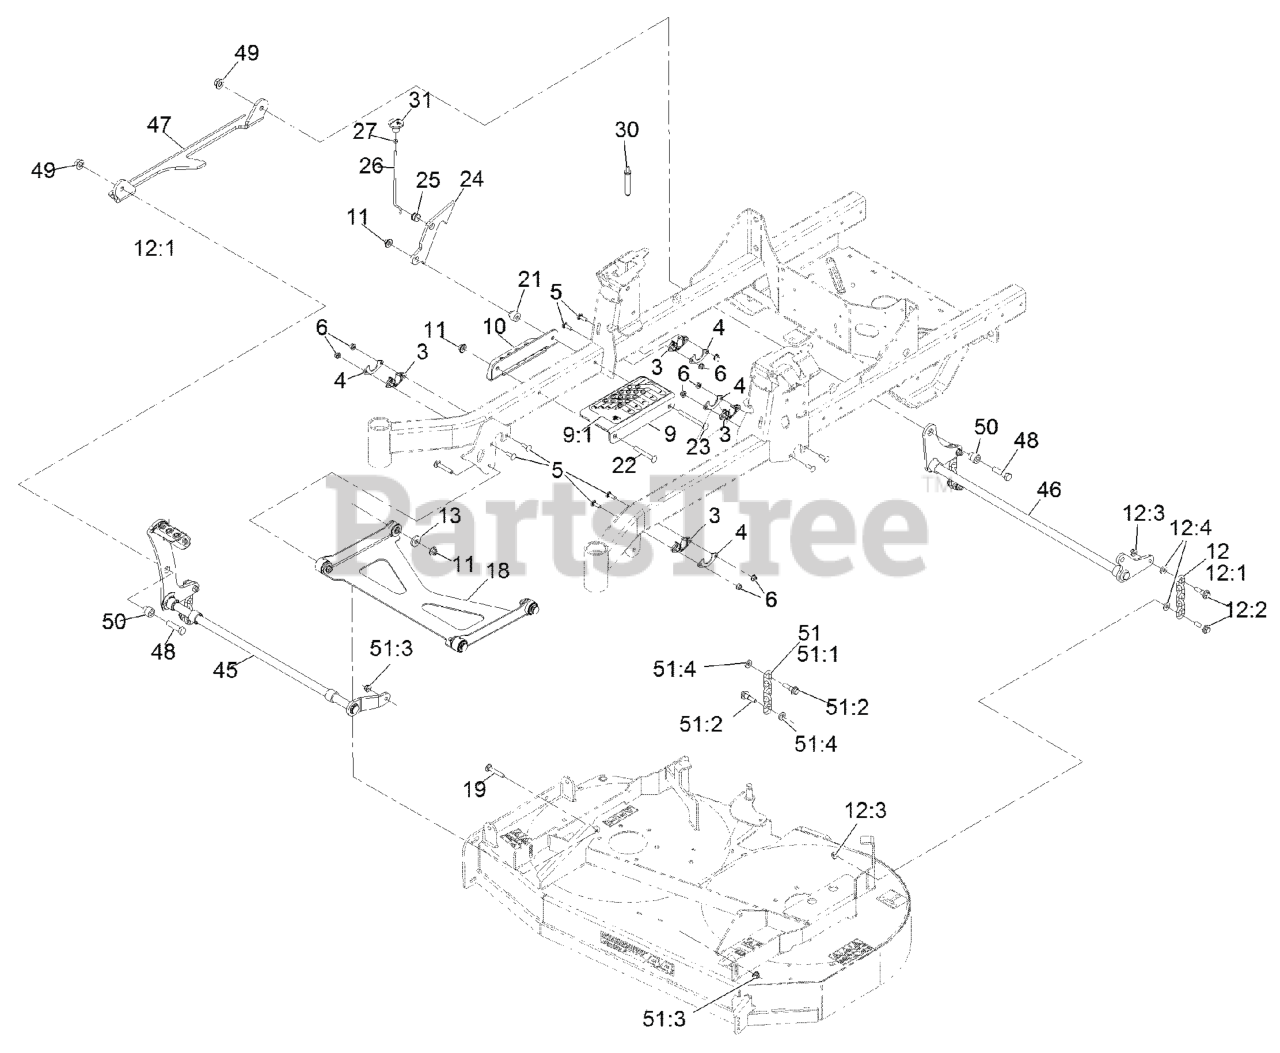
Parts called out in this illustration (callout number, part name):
3	BUSHING-FLANGE
4	GUSSET-LIFT, DECK
5	SCREW-CARR
6	NUT-HF, NI
9	BRACKET ASM
9:1	DECAL-HOC
10	ANGLE-HOC, LOWER
11	Nut-Nyloc 3/8-16 Flg
12	DECK CHAIN ASM
12:1	CHAIN-LIFT, DECK
12:2	BOLT-SHOULDER
12:3	NUT-HF, NI
18	DECK STRUT ASM
19	Bolt-Carriage 3/8-16 X 2 1/4
21	SPACER-STEPPED
22	SCREW-CARR
23	SCREW-CARR
24	PLATE-LOCK, TRANSPORT
25	GROMMET
26	ROD-LOCK, TRANSPORT
27	NUT-JAM
30	PIN-HOC
45	SHAFT-DECKLIFT FRONT
46	SHAFT-DECKLIFT REAR
47	LINK-DECKLIFT
48	SCREW-HH
49	Nut-Lock 1/2-13
50	Spacer-Stepped
51	Deck Chain ASM
51:1	CHAIN-LIFT, DECK
51:2	BOLT-SHOULDER
51:3	NUT-HF, NI
